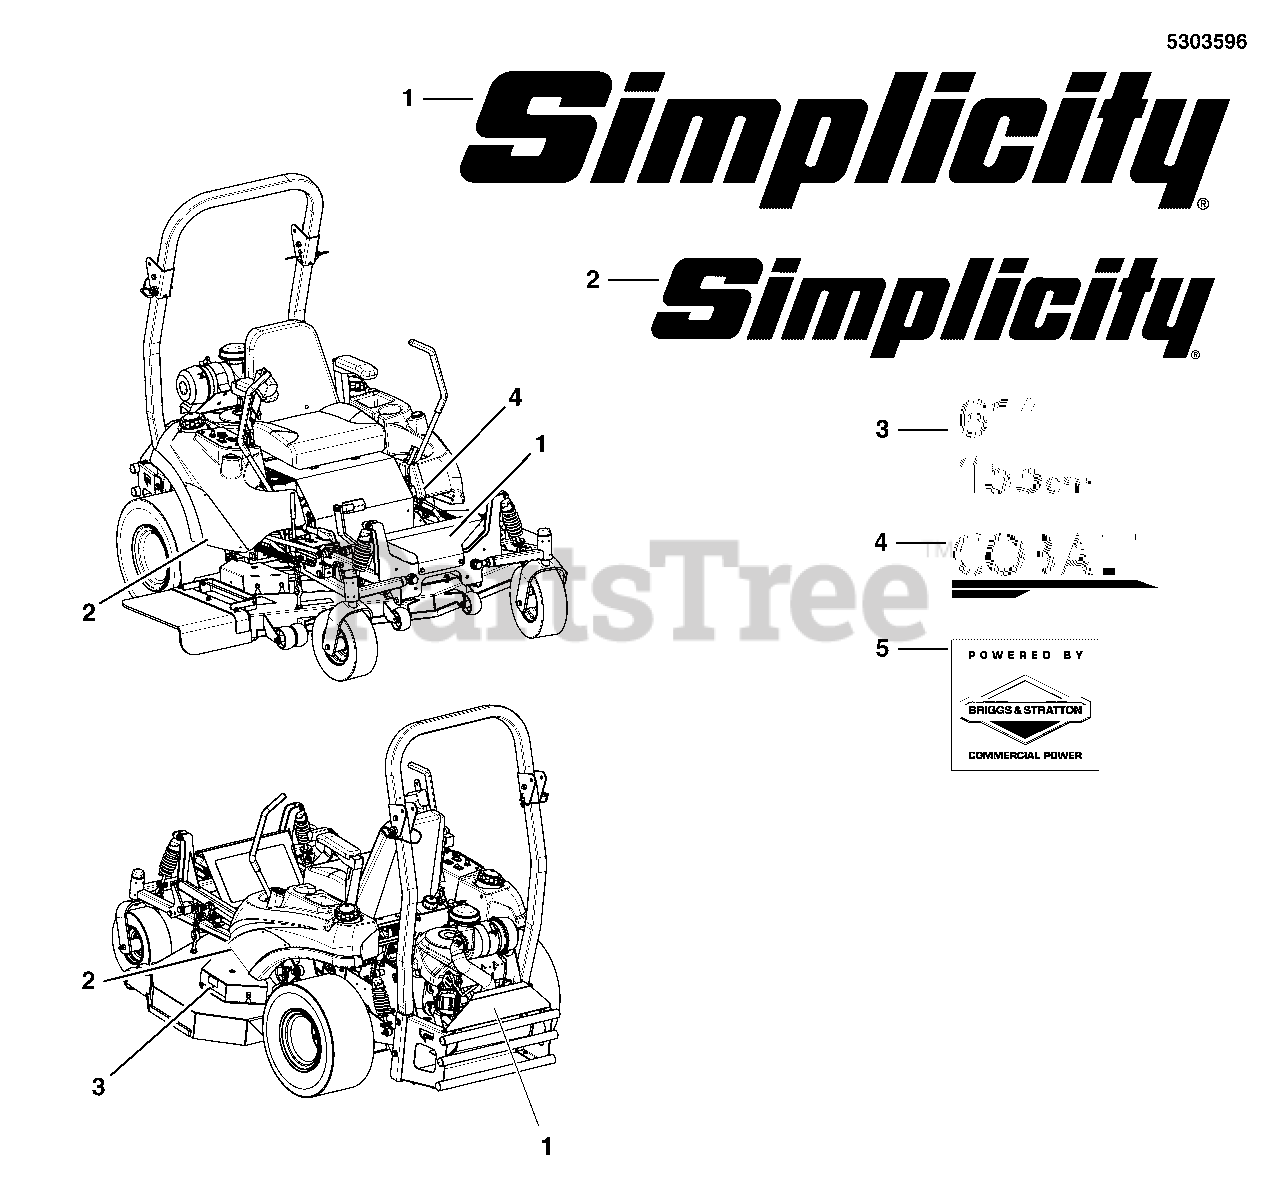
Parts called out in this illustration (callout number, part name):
1	DECAL, SMI LOGO 10.47"
2	DECAL, LOGO SIMPLICITY SILVER
3	DECAL, MOWER WIDTH 61IN/155CM
4	DECAL, LOGO, COBALT
